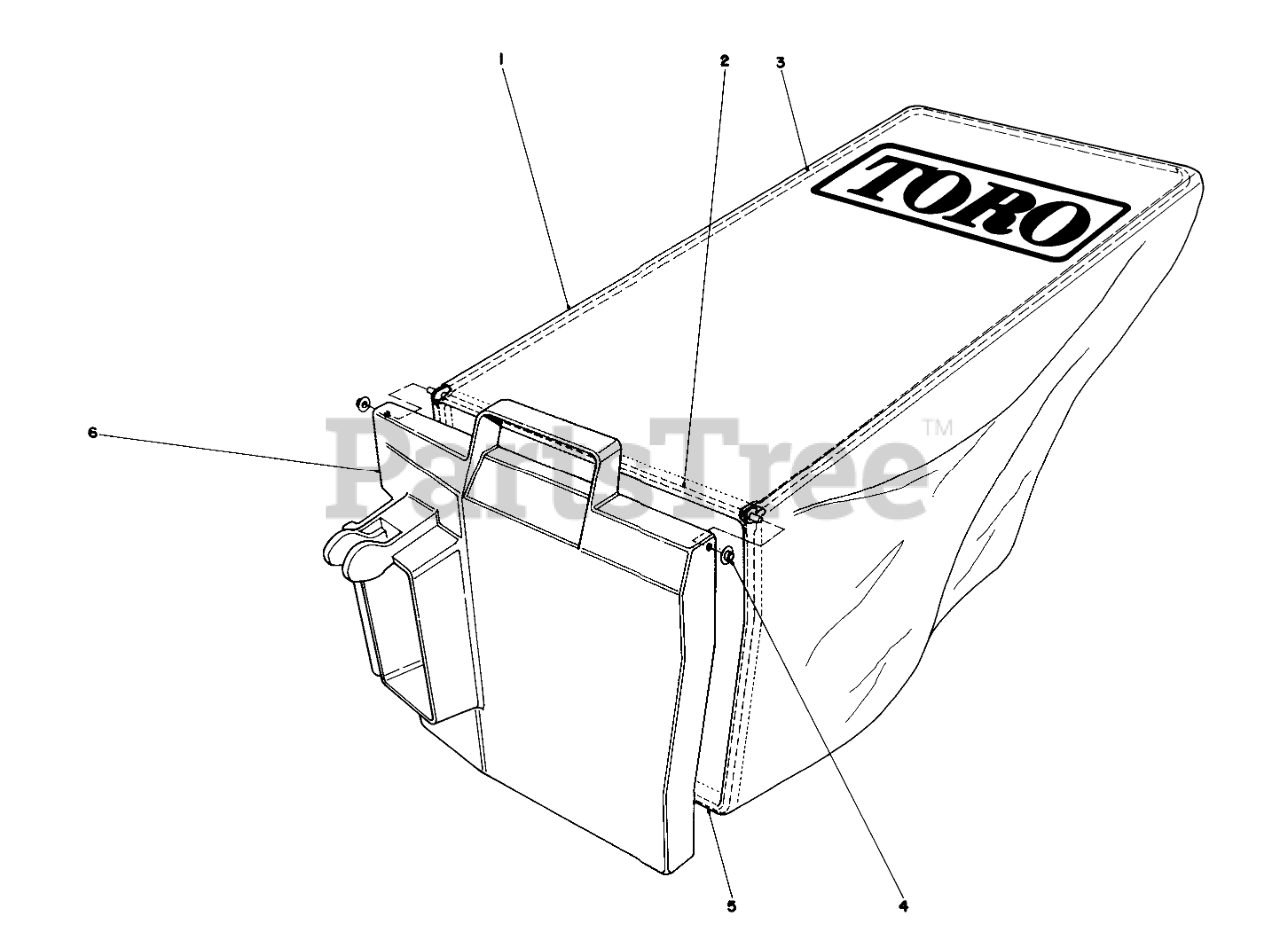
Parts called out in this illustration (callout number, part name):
1	Bag
2	HINGE PIN
3	BAG FRAME-UPPER
4	NUT-PUSH
5	Frame Bag
6	Door-Bag
